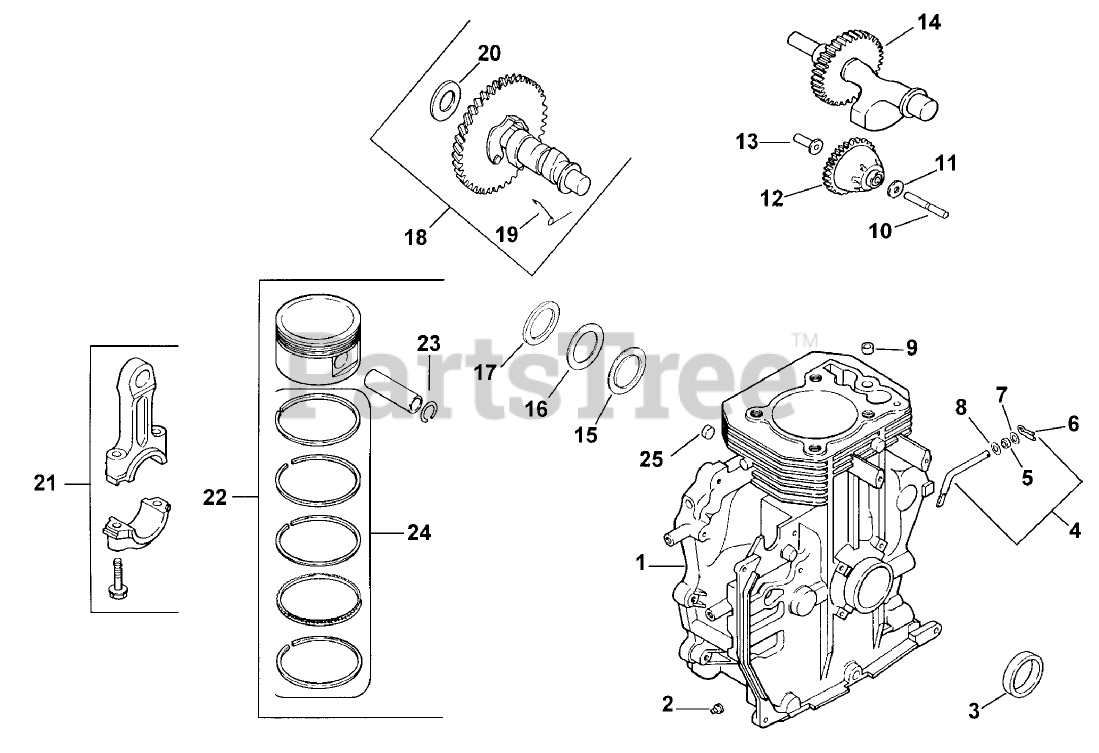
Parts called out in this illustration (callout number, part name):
1	Short Block
2	Plug
3	Seal-Crankshaft (Only On: 72042, 72043, 72062, 72063)
4	Kit-Governor Cross
5	Seal
6	Clip-Hitch Pin
7	Washer
8	Washer, plain 6 mm
9	Dowel-Locating
10	Shaft-Govenor Gear
11	Washer
12	Gear-Governor ASM (Only On: 72042, 72063, 72062, 72043)
13	Pin-Governor
14	Shaft, balance
15	Bearing, thrust
16	Washer, thrust
17	Shim, thrust
18	Kit-Camshaft INC 7-8 (Only On: 92003)
19	Spring-Actuating
20	Shim-Camshaft
21	Rod Connecting STD
22	Piston ASM STD INC 11-12 (Only On: 72042, 72063, 72062, 72043)
23	Retainer-Piston Pin (Only On: 72042, 72043,72062,72063)
24	Ring Set STD (Only On: 72042,72043,72062,72063)
25	Cup
